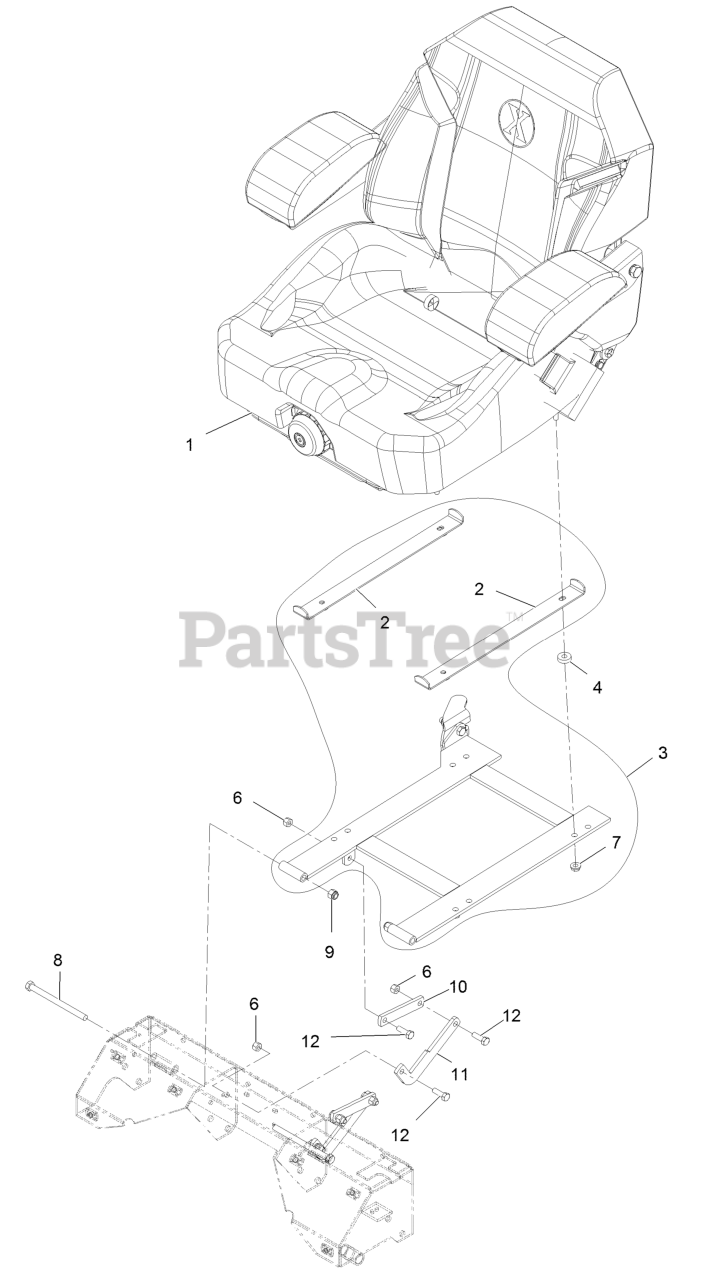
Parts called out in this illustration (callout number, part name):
1	KIT-SUSPENSION SEAT
2	STOP, SEAT
3	KIT,SEAT FRAME SERVICE
6	NUT-LOCK, NI
8	SCREW-HH
9	NUT-LOCK, NI
10	LINK-STOP, SEAT
11	LINK-STOP, SEAT
12	SCREW-HH
